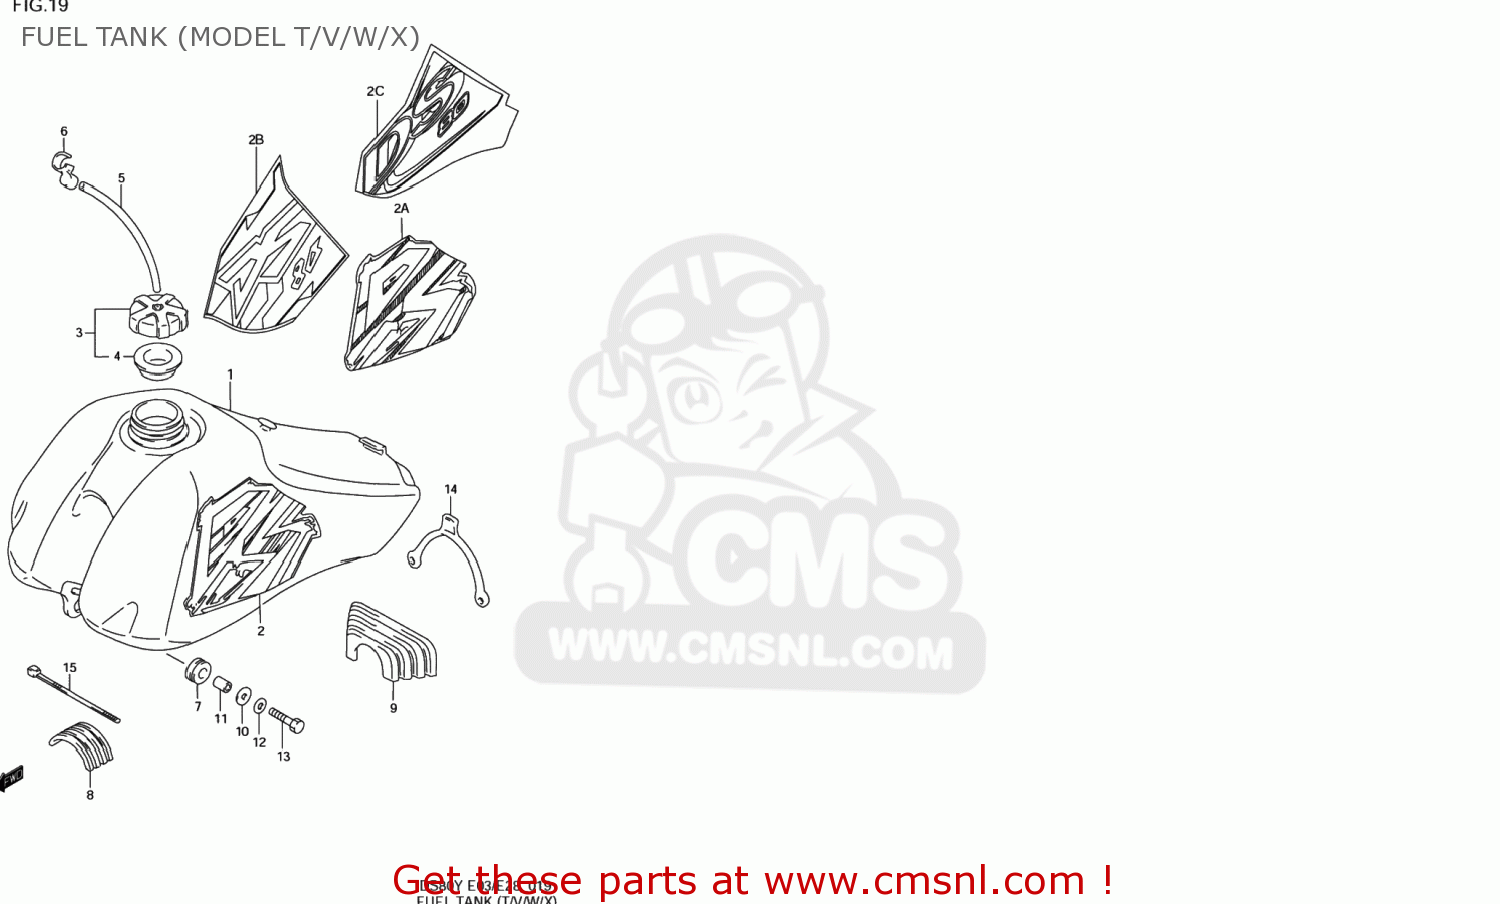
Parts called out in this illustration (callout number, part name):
1	TANK ASSY,FUEL(YELLOW)
2	EMBLEM SET,FUEL TANK
2A	EMBLEM SET,FUEL TANK
2B	EMBLEM SET,FUEL TANK
2C	EMBLEM SET,FUEL TANK
3	CAP SET,FUEL TANK
4	GASKET (NAS)
5	HOSE(5X8.2X600)
6	CLAMP
7	CUSHION
8	CUSHION,FUEL TANK UPR FR
9	CUSHION,FUEL TANK UPR RR
10	WASHER(6.5X24X1.6)
11	SPACER(6.5X10X13.5)
12	LOCK WASHER
13	BOLT
14	BAND,FUEL TANK RR
15	CLAMP
